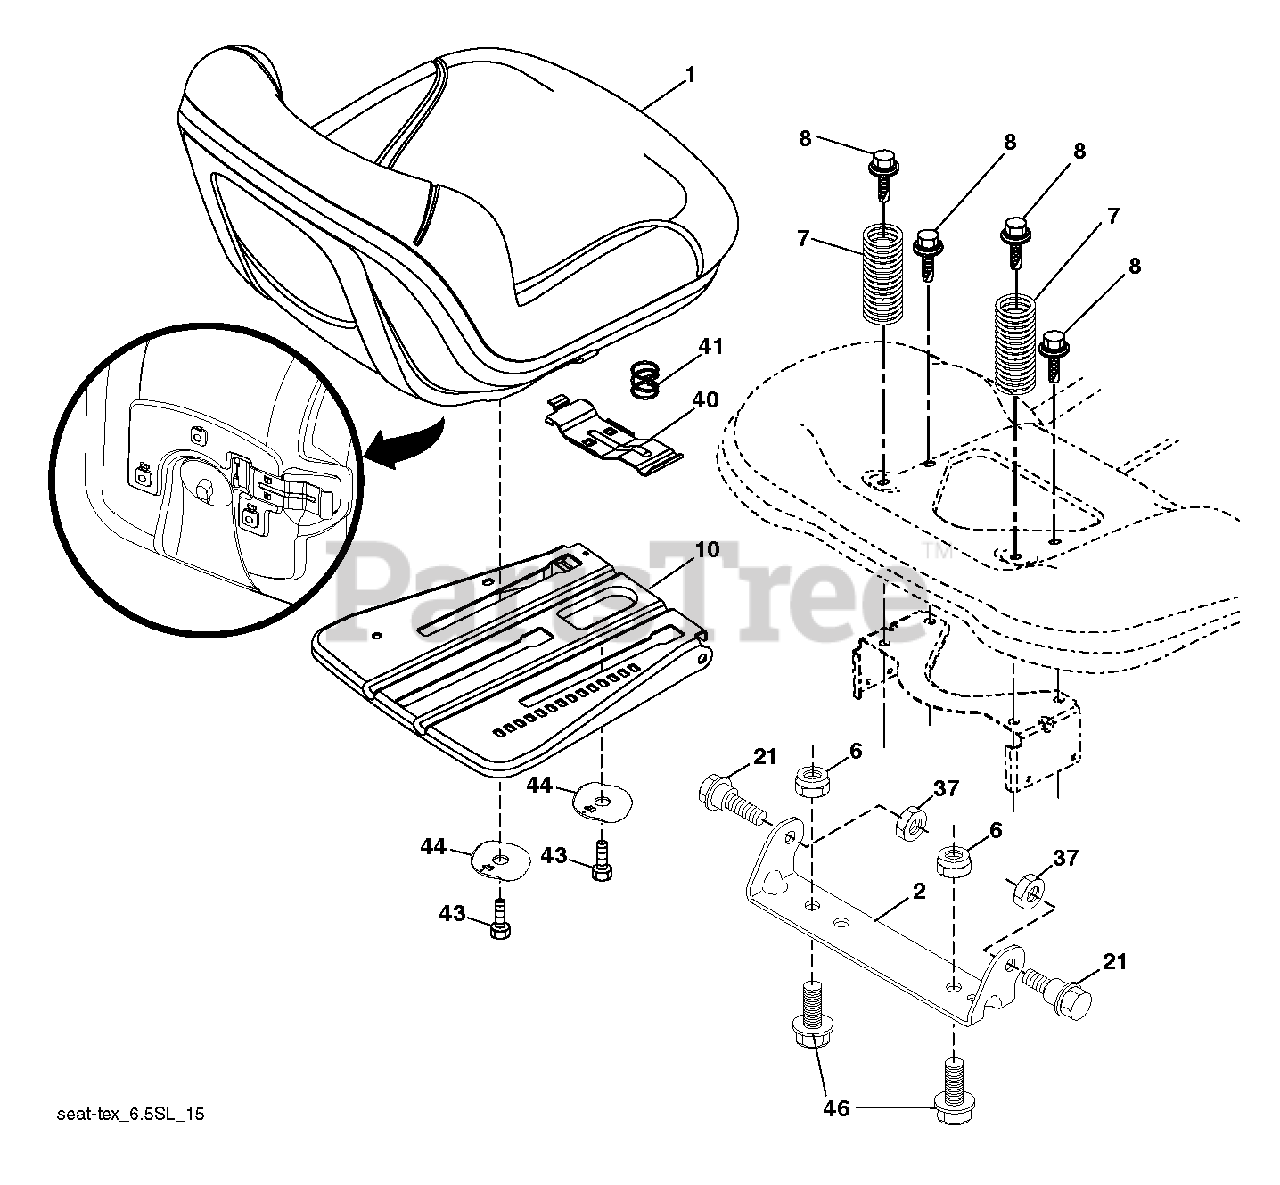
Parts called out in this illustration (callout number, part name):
1	SEAT.TH130.GREY.HUSQ.TEX
2	BRKT.PIVOT.FENDER
6	NUT
7	SPRING.COMPRESS.SEAT.
8	BOLT, 5/16-18 X 1 3/4
10	Seat Slide Plate, Pnt
21	BOLT.5/16-18X5/8.SHOULDER
37	NUT.71038.31-18.HEX.NYLOCK
40	HANDLE.SLIDE.SEAT.TEX.GREY
41	SPRING.LATCH.SEAT.TEX
44	Winged Washer, 38Id 1
46	BOLT.3/8-16X1;1.25OD.WSHR.SEMS
